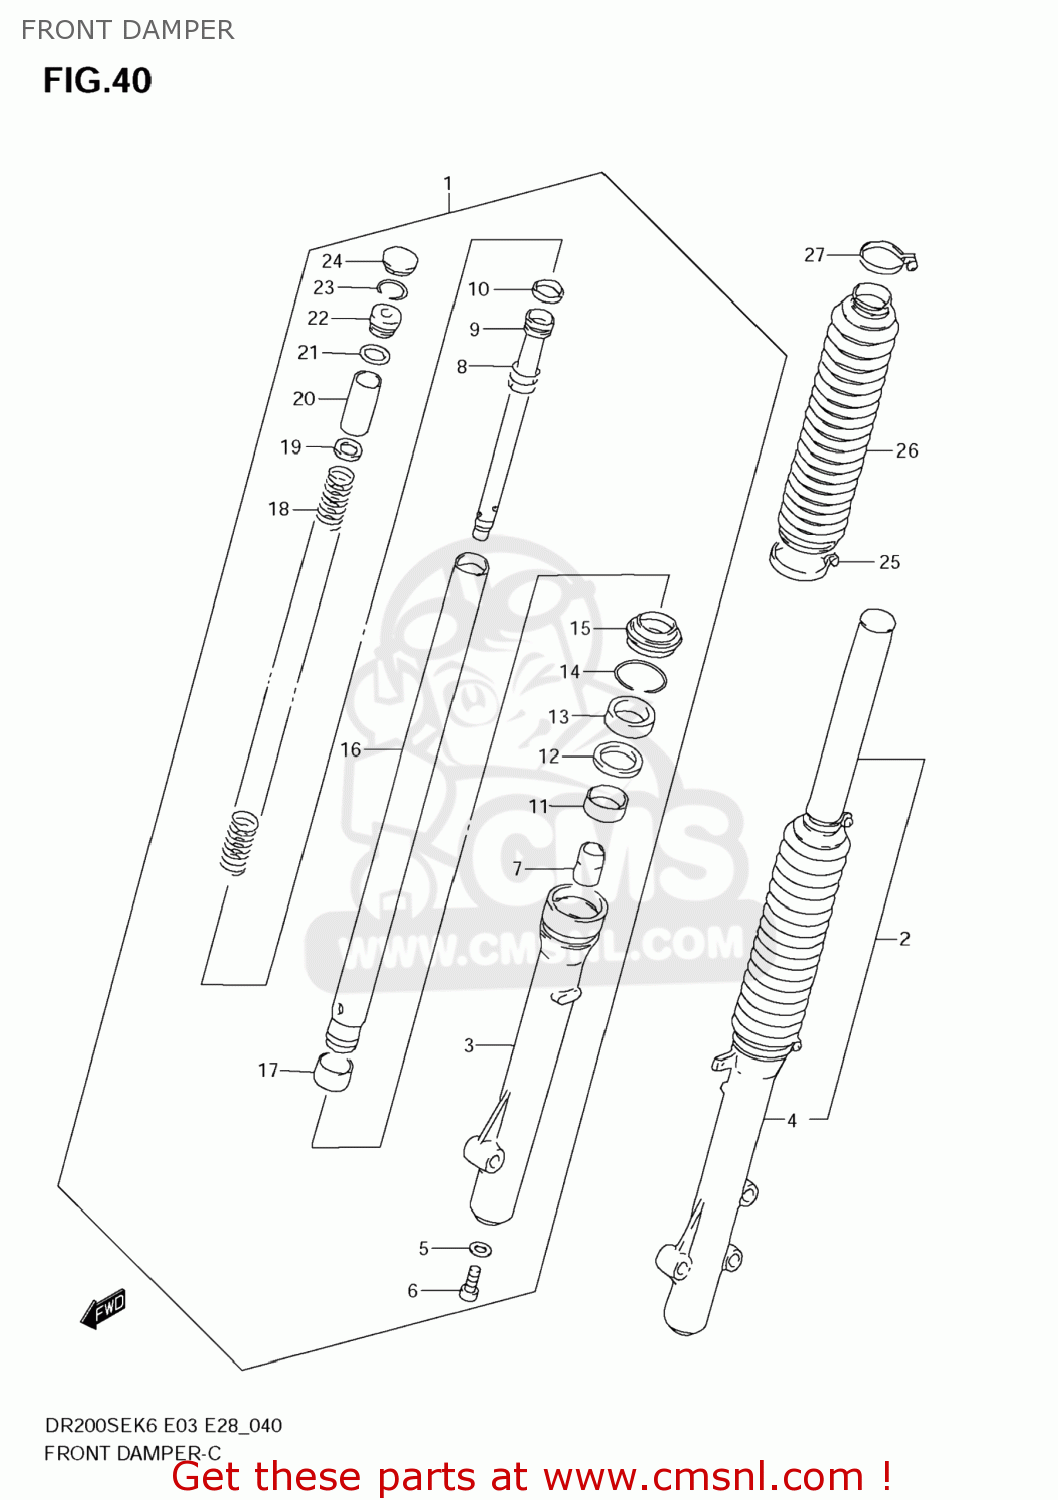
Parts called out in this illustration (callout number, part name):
1	DAMPER ASSY,FR FORK,R
2	DAMPER ASSY,FR FORK,L
3	TUBE,OUTER,R
4	TUBE,OUTER,L
5	GASKET (NAS)
6	BOLT
7	PIECE,OIL LOCK
8	SPRING,REBOUND
9	CYLINDER
10	RING,PISTON
11	BUSH,GUIDE
12	SPACER,SEAL
13	SEAL,OIL 35X48X11
14	RING,OIL SEAL STOPPER
15	SEAL,DUST
16	TUBE,INNER
17	PISTON
18	SPRING,MAIN
19	SPRING,JOINT
20	SPACER,SPRING
21	O RING
22	SPRING SEAT B
23	RING,STOPPER
24	CAP
25	BAND,BOOT LWR
26	BOOT
27	BAND
